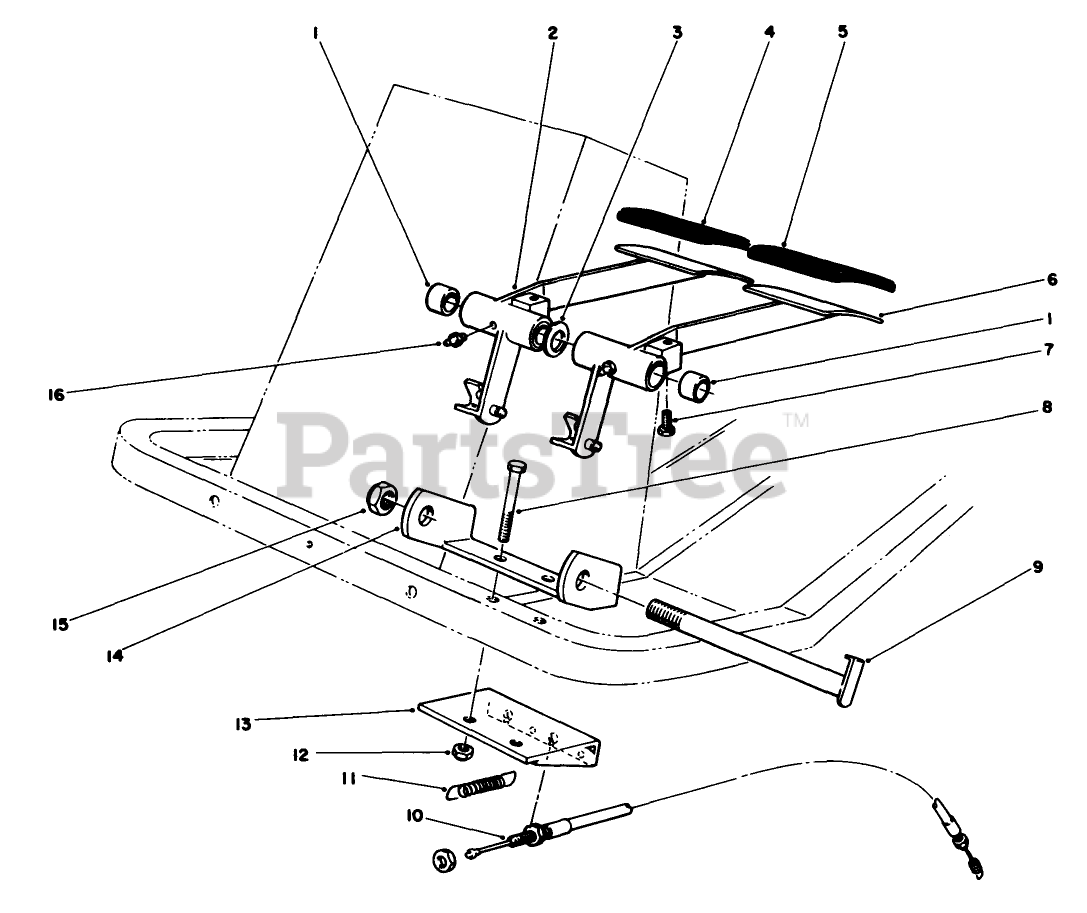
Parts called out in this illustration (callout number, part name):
1	BUSHING
2	Brake Pedal Assembly-R.H. (Incl. Ref. #1 & 16)
3	WASHER-FLAT
4	PAD-TURN, RIGHT
5	PAD-TURN, LEFT
6	Brake Pedal Assembly-L.H. (Incl. Ref. #1 & 16)
7	BOLT 60183
8	SCREW-HH
9	BRAKE PIN WA RO
10	BRAKE CABLE ASM
11	EXTENSION SPRING O
12	NUT-LOCK, NI
13	CABLE BRKT WA R
14	BRAKE PEDAL BRKT B
15	NUT-LOCK, NI
16	FITTING-GREASE
